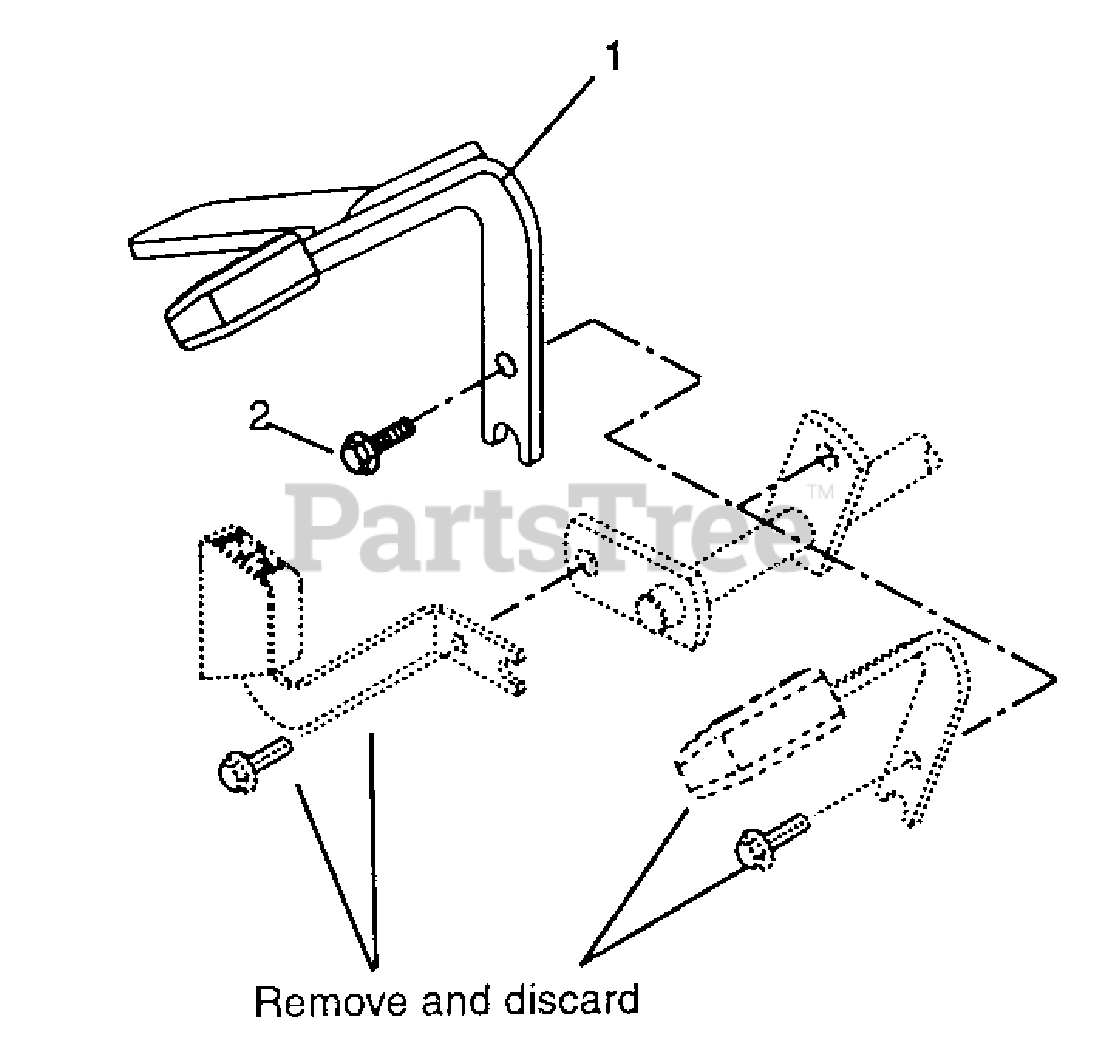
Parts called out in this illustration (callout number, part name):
1	Pedal, Fwd/Rev
1	Cover, Pedal
2	Screw, Tapping
